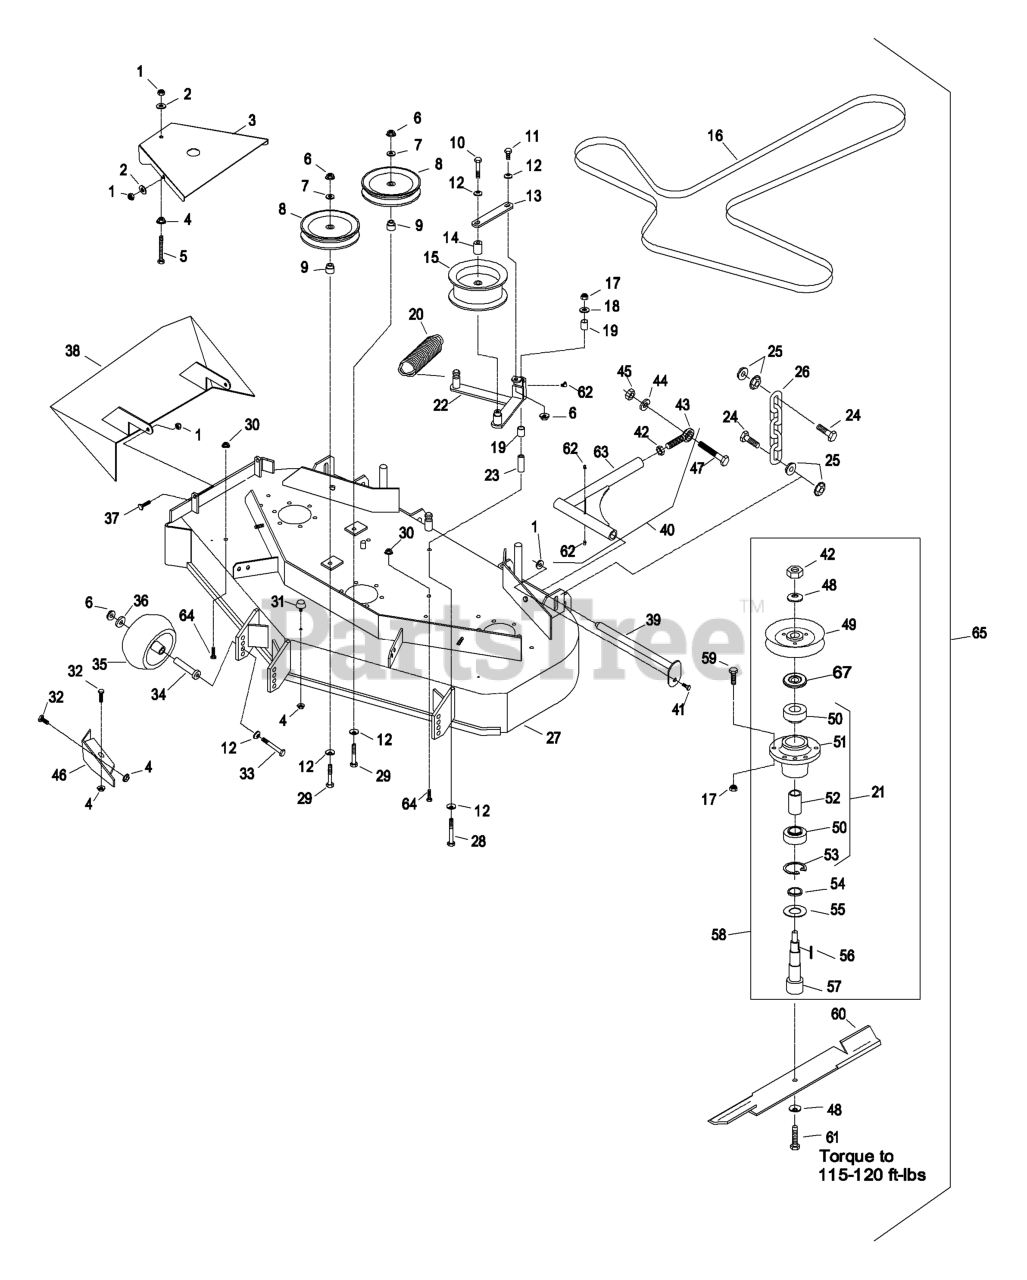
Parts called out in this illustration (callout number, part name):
1	NUT-LOCK, NI
2	WASHER-FLAT
5	BOLT,TAP HH
6	NUT-HHF, WHIZ
7	WASHER-FLAT
8	PULLEY-IDLER
9	BUSHING-IDLER
10	SCREW-HH
11	SCREW-HH
12	WASHER-BELLEVILLE
16	BELT,DECK DRIVE
17	NUT-LOCK, NI
18	WASHER-FLAT
19	SLEEVE-BEARING
23	BUSHING-PIVOT, IDLER
24	SCREW-CAP, HH
26	CHAIN-LIFT, DECK
27	ASM,DECK W/DECALS LHP48 S
28	WASHER-LOCK
29	SCREW-HH
31	BUMPER-RUBBER
32	SCREW-HH
33	SCREW-HH
34	BUSHING-ROLLER
35	ROLLER-SCALP, ANTI
37	SCREW-HH
38	WLD,CHUTE 48
39	PIN-STRUT
40	STRUT ASM
41	SCREW-HH
42	NUT-HEX
43	BALLJOINT-SPHERICAL
44	WASHER-LOCK
45	NUT-HEX
48	WASHER-SPRING
49	SHEAVE,W/HUB 5.72
50	BEARING
52	SPACER-BEARING
54	SPACER-PULLEY/BEARING
55	GUARD-BEARING, BOTTOM
56	KEY-RECTANGLE
57	SHAFT,SPINDLE
58	ASM,CUTTER HSG SERVICE
59	SCREW-HH
61	SCREW-CAP
62	FITTING-GREASE
64	SCREW-HH
65	Deck Complete Service (44")
66	WASHER-BLADE BOLT, HEAVY
67	GUARD-BEARING, TOP
